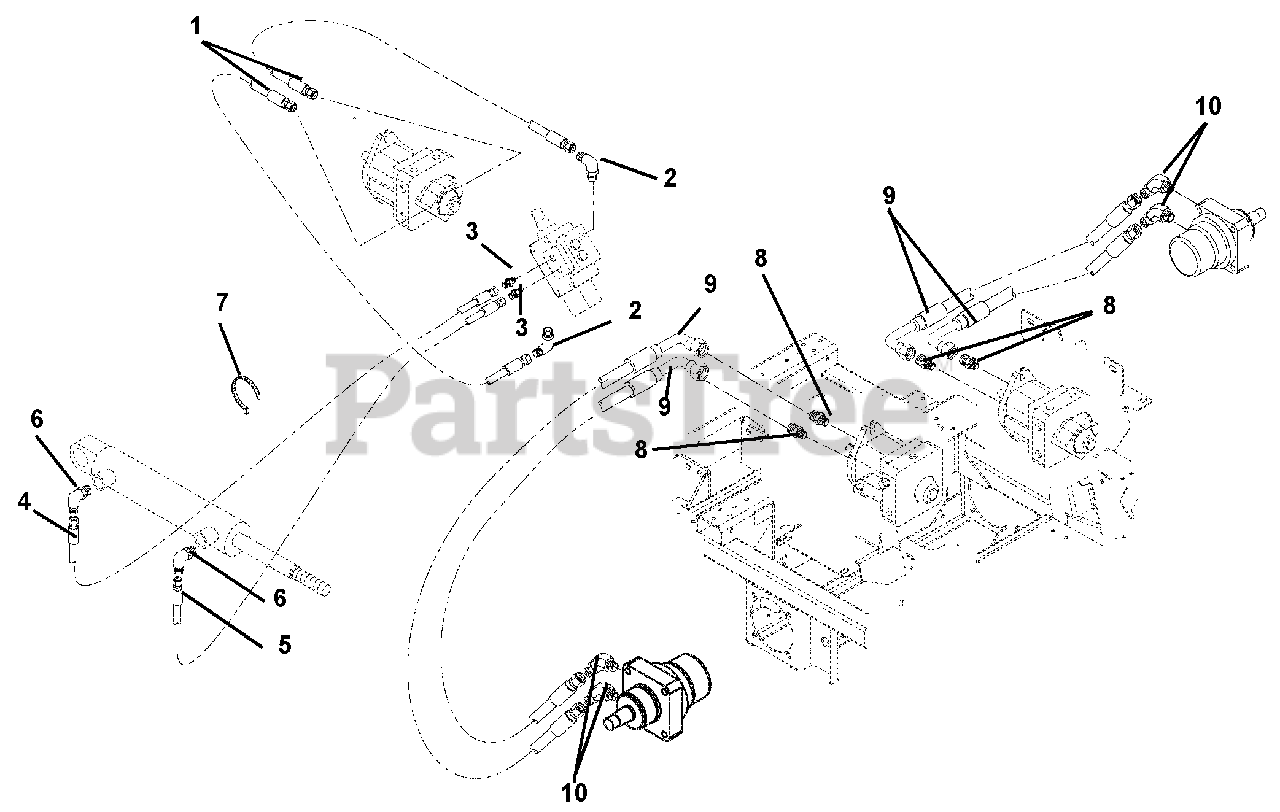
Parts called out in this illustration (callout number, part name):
1	HOSE,HYD.25-22-2K F04F9-F06FO
2	FTG, HYD ELBOW M6F-M8O
3	FITTING, HYD (4-6 F5OLO)
4	HOSE,HYD.25-42-2K F04F0-F04F4
5	HOSE,HYD .25-47-2K F04F0-F04F4
6	FITTING, HYD (4 C5OLO)
7	CABLE TIE LG 5-1/2
8	ADPTR,FACE SEAL 8X8 1/2 O-RING
9	HOSE,HYD .50-17-2K F08F0-F08F9
10	FITTING, HYD (8-10 V5OLO)
